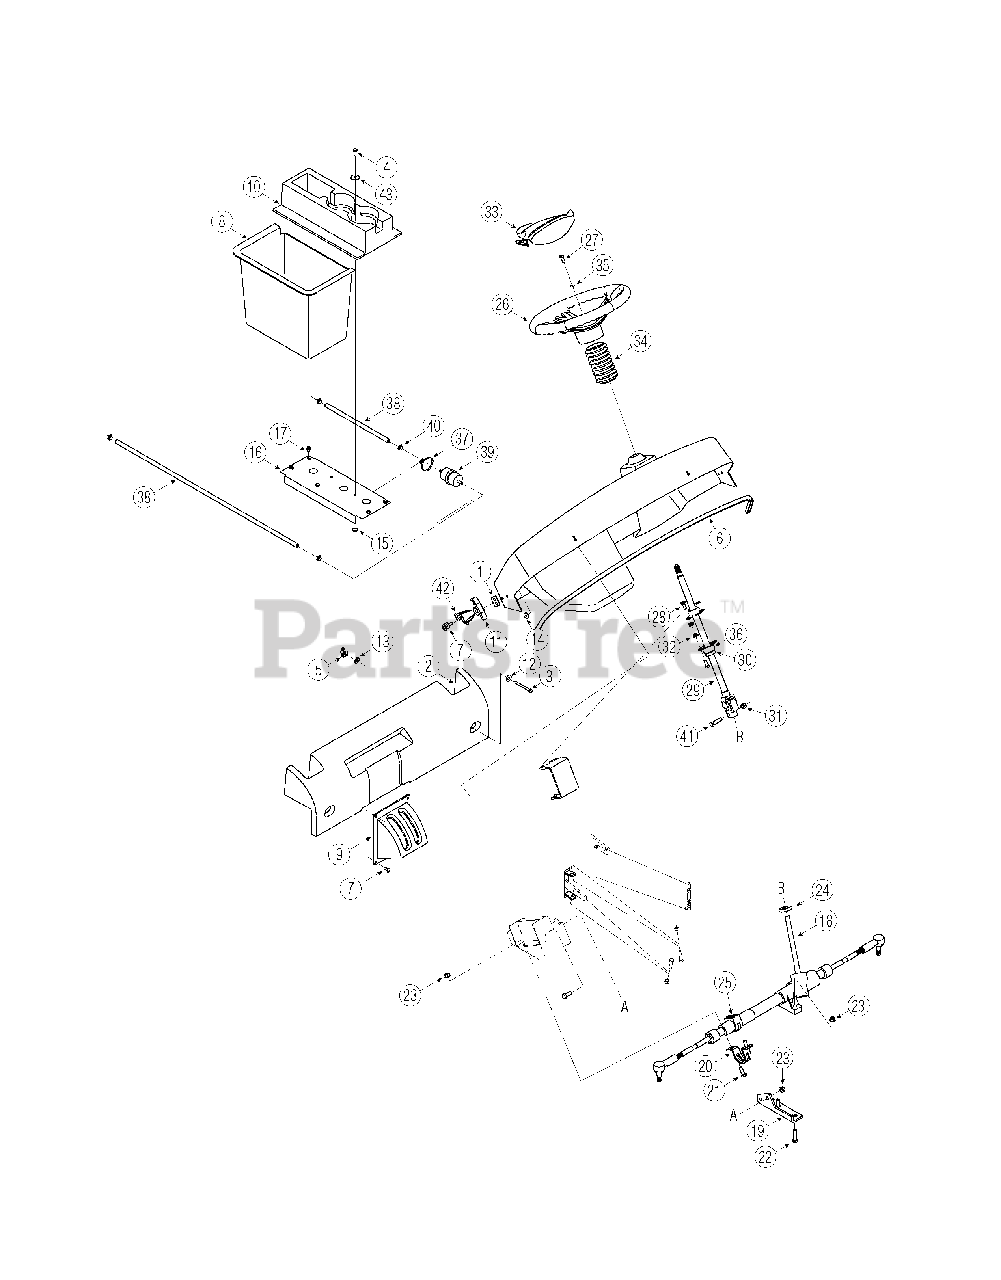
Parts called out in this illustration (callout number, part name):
1	Hood Mounting Plate
2	Panel, Airbox Cover
3	Hex Screw, 1/4-20 x 2.75
4	Hex Screw, 5/16-18 x0.5, Gr5
5	Wing Nut, 1/4-20
6	Trim, Bulb Seal, 1/4
7	Rivet, Pop,.188
8	Container, Bulkhead
9	Panel, Shift Cover
10	Console, Cup Holder
11	Handle, Latch
12	Flat Washer, 349 x.875 x.04
13	Washer, Flat,.28 x.74 x.063
14	Washer, Flat,.194 x.62 x.063
15	Washer, Flat,.25 x.630 x.0515
18	Gear Assembly, Steering
21	Hex Screw, 3/8-16, 1.00, Gr8
22	Hex Screw, 3/8-16, 1.50, Gr5
23	Nut, Flange Lock, 3/8-16
24	Grommet, Steering Shaft
25	Bushing, Rubber
26	Wheel, Steering
27	Hex Screw, 5/16-18,.75, Gr5, Patch
28	Hex Screw, 5/16-18, .75, Gr5
29	Shaft, Steering, 5/8 Spline
30	Collar, .75
31	Nut, Hex Lock Nylon, 3/8-16
32	Nut, Flange Lock, 5/16-18
33	Cover, Steering Wheel
34	Bellow, Steering, 4.75 Lg
35	Washer, Bell,.340 x.872 x.060
36	Bearing, Flange,.75 ID, Self-Aligning
37	Cable Tie
38	Fuel Line Hose
39	Fuel Filter
40	Clamp, Hose
41	Hex Screw, 3/8-16 x 1.75, Gr5
42	Rivet. Pop, .450
43	Washer, Bell .39 x 1.38 x .062
